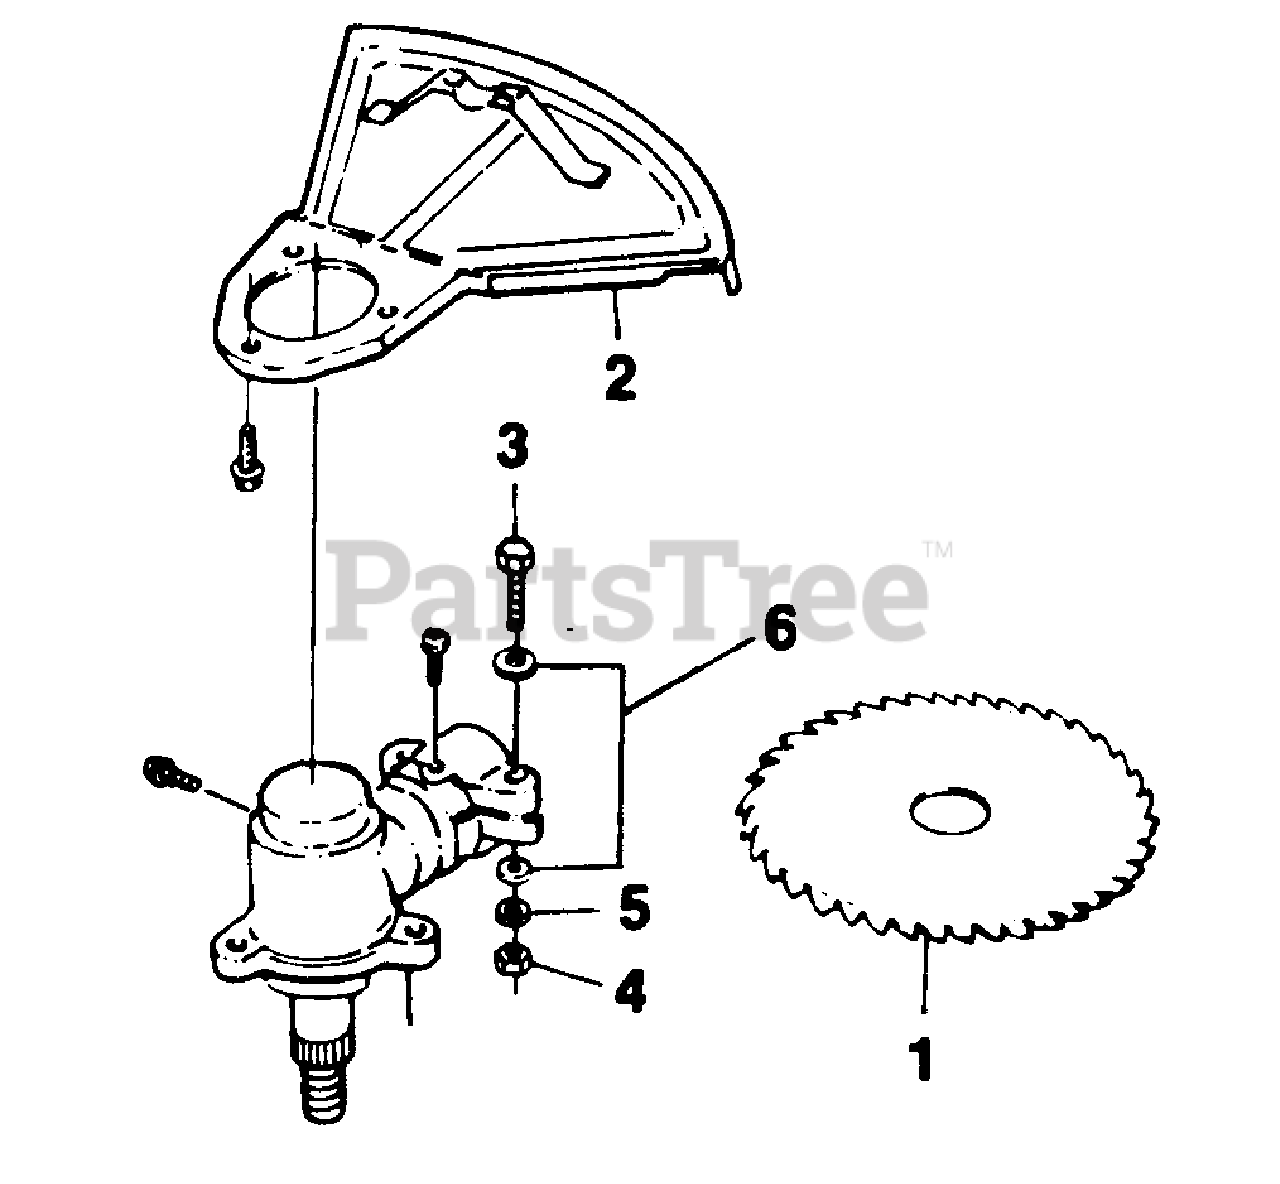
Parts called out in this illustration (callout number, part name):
1	BLADE- 50 tooth
2	DEFLECTOR
4	NUT
5	WASHER- Flat
6	WASHER- Spring
